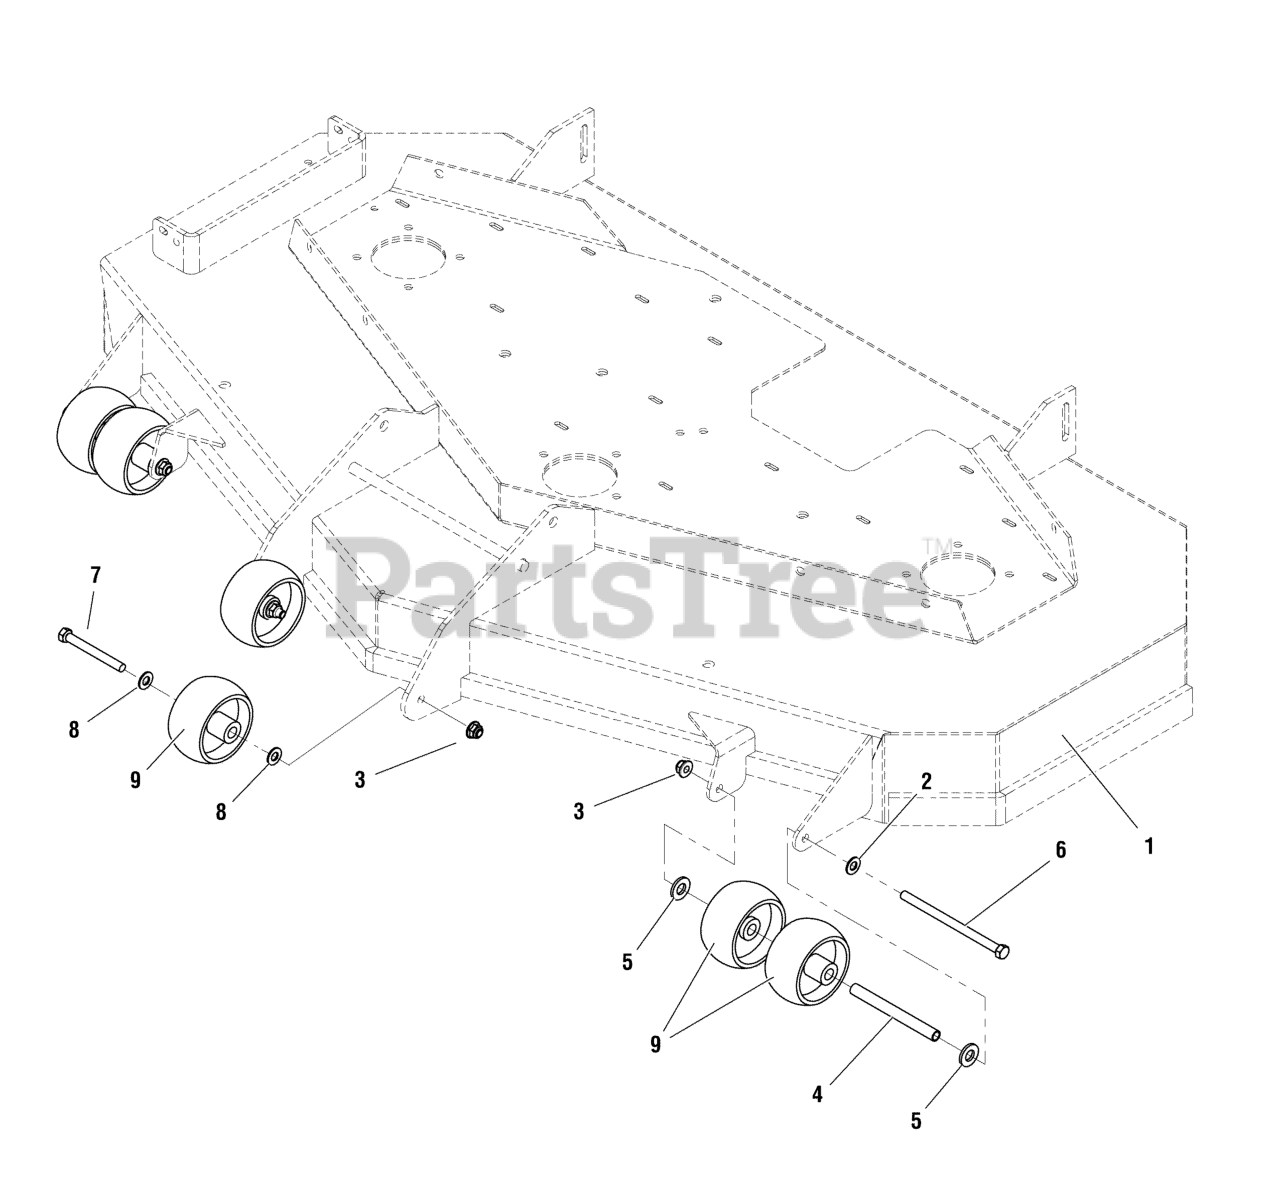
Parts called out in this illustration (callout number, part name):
1	MOWER DECK (SEE HOUSING, COVERS, SPINDLES & BLADES GROUP
2	WASHER, 3/8 SAE
3	NUT, 3/8-16 Hex Side Lock
4	SPACER, .38 X .50 X 5.06
5	WASHER, 1/2 SAE
6	BOLT, 3/8-16 X 6" GD5 CZ
7	BOLT, REAR WHEEL
8	WASHER,.516IDX.875ODX.06,FLAT,ZC/CL
9	WHEEL- 2.00 WIDE 3.88 DIA 0.531ID POLY
